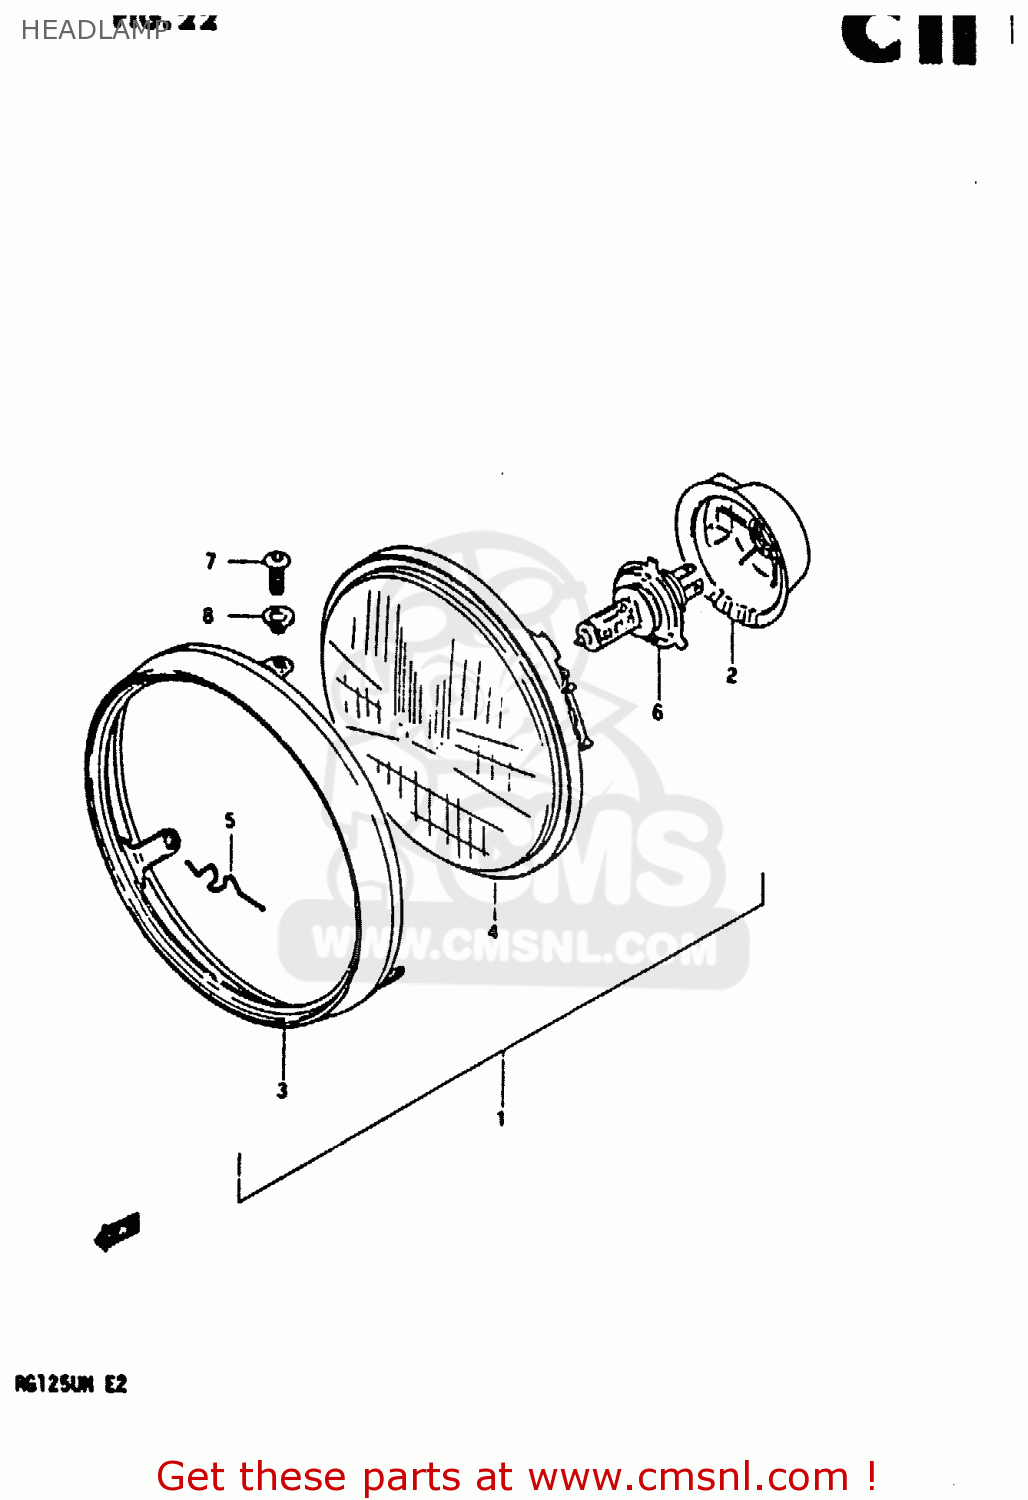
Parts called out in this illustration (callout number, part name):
1	HEADLAMP ASSY
2	COVER,SOCKET
3	RIM
4	UNIT
5	SPRING
6	BULB(12V60/55W,H4)
7	SCREW
8	WASHER
